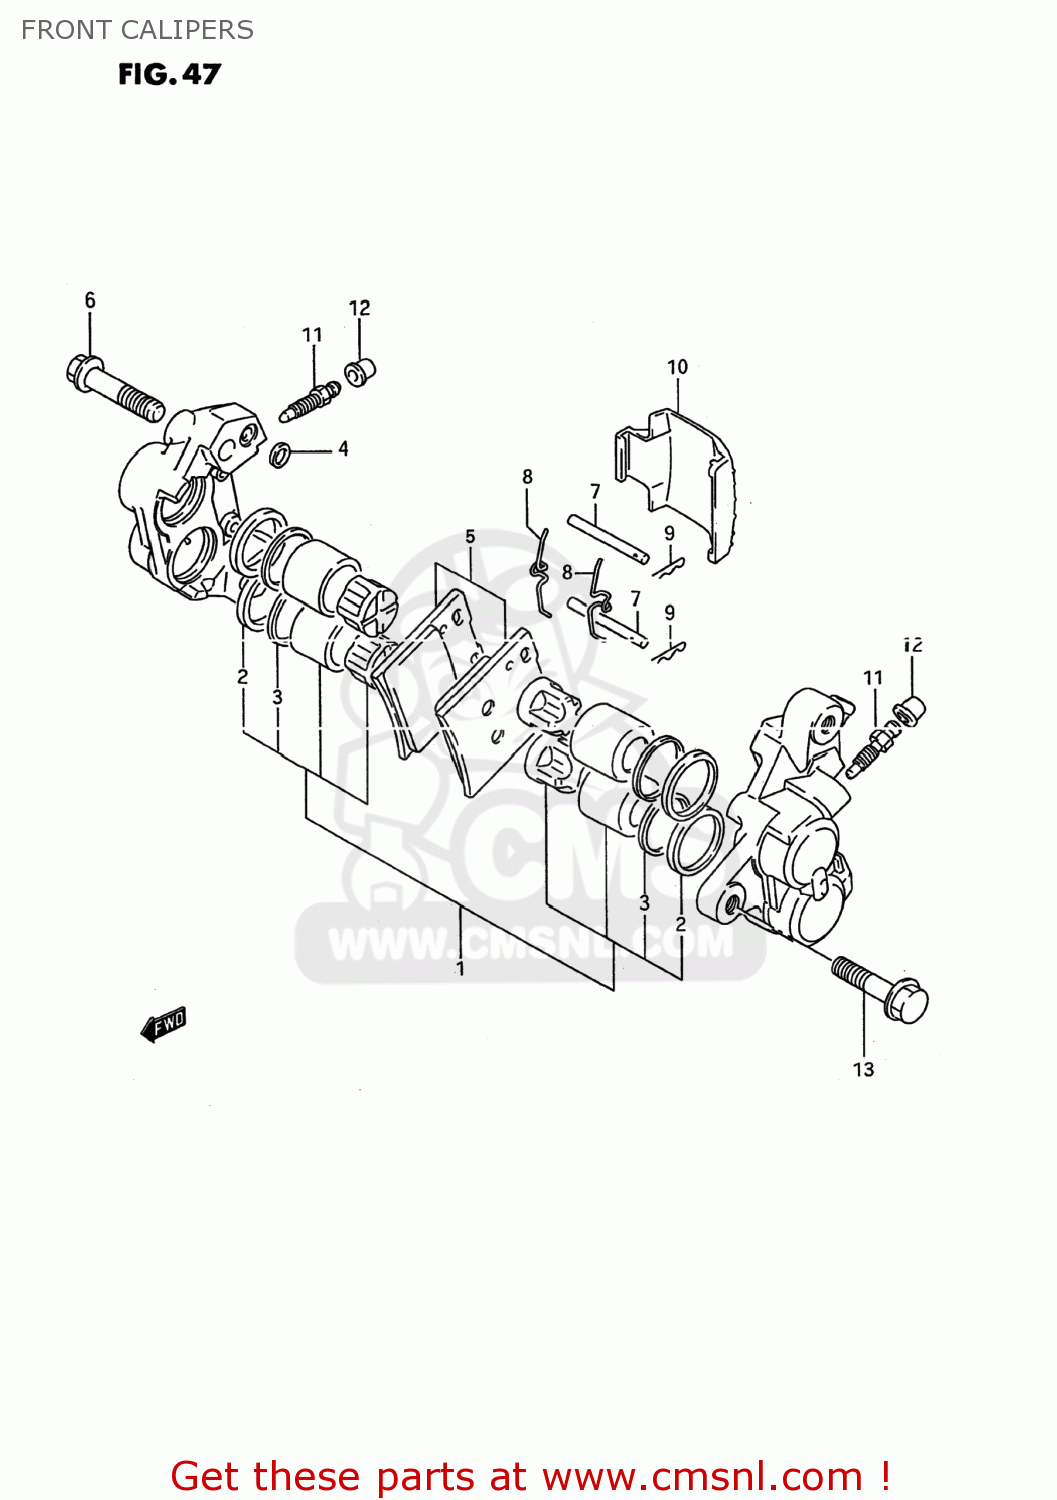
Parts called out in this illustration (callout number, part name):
1	PISTON SET
2	SEAL,PISTON
3	SEAL,WIPER
4	SEAL,JOINT
5	PAD SET (NAS)
6	BOLT,HOUSING
7	PIN,PAD
8	SPRING
9	CLIP,PAD PIN
10	COVER,CALIPER
11	BLEEDER
12	CAP,BLEEDER PLUG
13	BOLT
